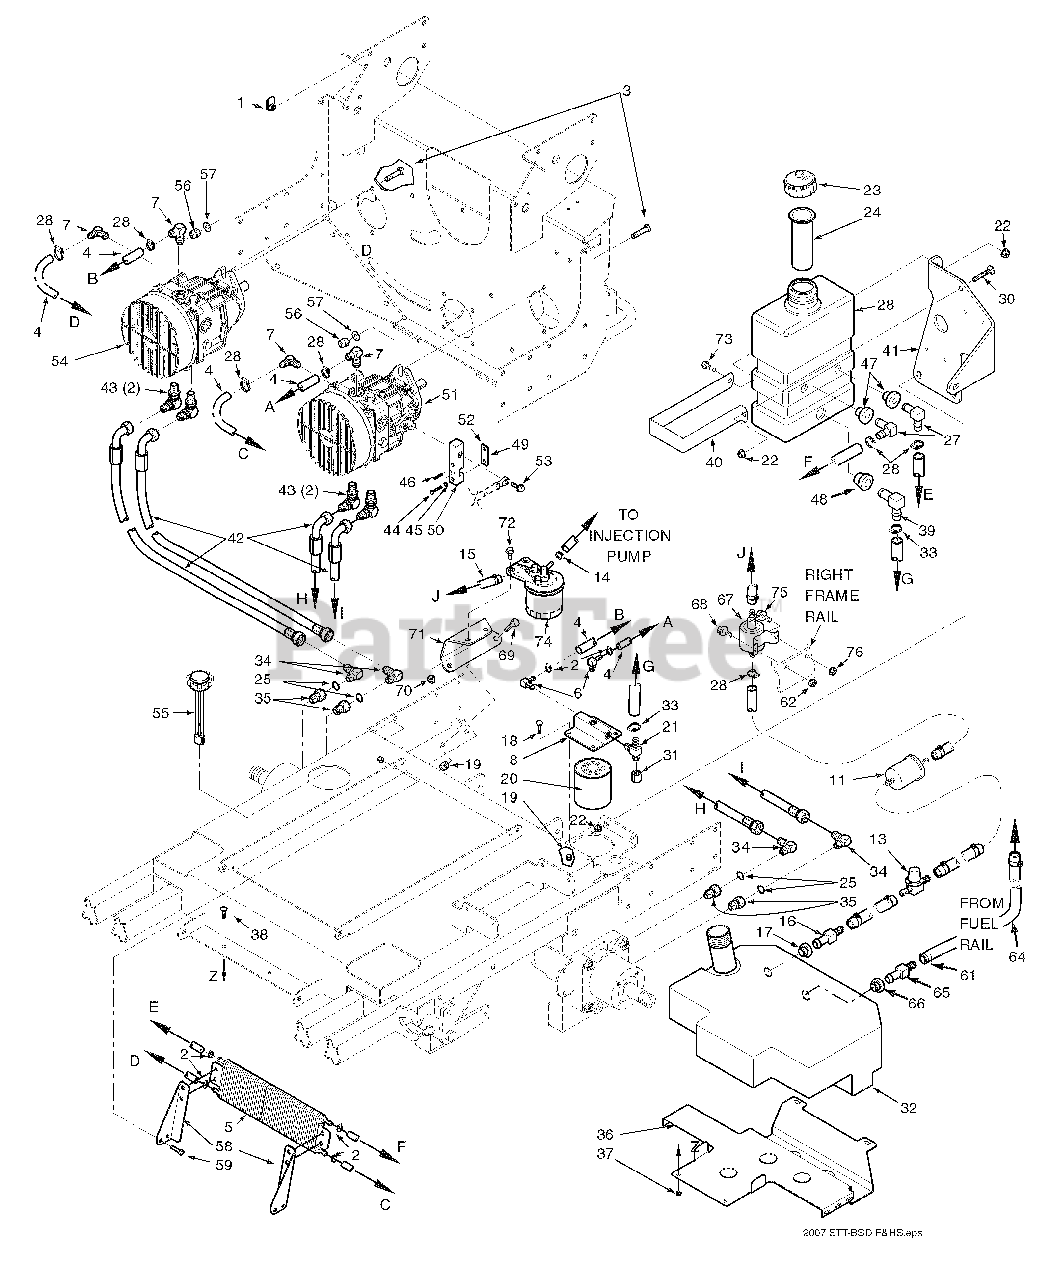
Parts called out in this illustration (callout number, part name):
1	U-Nut 1/4-20
2	Hose Clamp, 0.69 dia.
3	Bolt, Hex Head 1/4-20 x 2.0"
4	Hose, 3/8" ID Pushlock -
5	Oil Cooler
6	Elbow, 90 Degree - 1/4 NPT x 3/8 Hose
7	Elbow, 90 Degree - 9/16 O-ring x 3/8" Hose
8	Oil Filter Base
9	Hose Assembly, 1/2" ID
10	Clamp, .87 max Dia.
11	Fuel Pre-Filter, Kubota
12	Fuel Hose, 5/16" ID. Non-Perm.
13	Valve, Shutoff
14	Clamp, Fuel Hose
15	Fuel Hose, 5/16" ID. Non-Perm
16	Hose Fitting
17	Bushing
18	Bolt, Hex Head 5/16-18 x1.0" Zinc
19	Nut, Serrated Flange 5/16-18
20	Oil Filter
21	Tee, 3/4 O-ring x JIC x 1/2" Hose
22	Nut, Hex Elastic Stop 1/4-20
23	Cap, Hydraulic Tank
24	Insert, Filler Neck
25	O-Ring
26	Oil Reservoir Assembly
27	Elbow, 90 Degree .38 Hose
28	Hose Clamp, 0.69 dia.
29	Hose, 3/8" ID, Pushlock
30	Screw, Phillips Head, 1/4-20
32	Fuel Tank Assembly
33	Clamp, Hose
34	Elbow, 90 Degree, 7/8-14 THD
35	Bushing, 7/8-14 JIC x 3/4-16 O-Ring
36	Support Bracket, Fuel Tank
37	Nut, 5/16-18 Serrated Flange
38	Bolt, Carraige 1/4-20 x 3/4"
39	Elbow, 90 Degree
40	Strap, Hydraulic Tank
41	Support Bracket, Hydraulic Tank
42	Hose Assembly, Pump
43	Union, 3/4-16 JIC x 3/4-16 O-ring
44	Bolt, Hex Head, 1/4-20 x 1-14"
45	Lockwasher, 1/4" Spring
46	Roll Pin, Spring 3/16 x 3/4"
47	Bolt, Hex Serrated Flange, 1/4-20 x 3/4"
48	Fuel Hose, 5/16" ID. Non-Perm
49	Clamp Plate, Pump Control
50	Block, Pump Control
51	Pump, Left Hand, BDP-16A
52	Nut, Hex, Elastic Stop 3/8-16
53	Bolt, Hex Head, 3/8-16 x 1-1/4
54	Pump, Right Hand, BDP 16A
55	Cap, Fuel Tank W/Gauge
56	Nut, Hex Elastic Stop 3/8-16
57	Flatwasher, 3/8" Grade 8
58	Mounting Bracket - LH, Oil Cooler
59	Bolt, Hex Head 5/16-18 x 3/4"
60	Cooler, Oil
61	Clamp, .69 Dia.
62	Nut, Serrated Flange 5/16-18
64	Hose, 1/4" Fuel Line
65	Fitting, Hose
66	Bushing
67	Fuel Pump, Kubota
68	Bolt, Hex Head 5/16-18 x 3/4"
69	Bolt, Hex Head 3/8-16 x 1"
70	Nut, Elastic Stop 3/8-16
71	Bracket, Fuel Filter Mounting
72	Bolt, Hex Head Serr. Flange 5/16-18 x 3/4"
73	Bolt, Hex Head 1/4-20 x 3/4"
74	Fuel Filter
75	Bolt, Hex Head 1/4-20 x 3/4"
76	Nut, Serrated Flange 1/4-20
